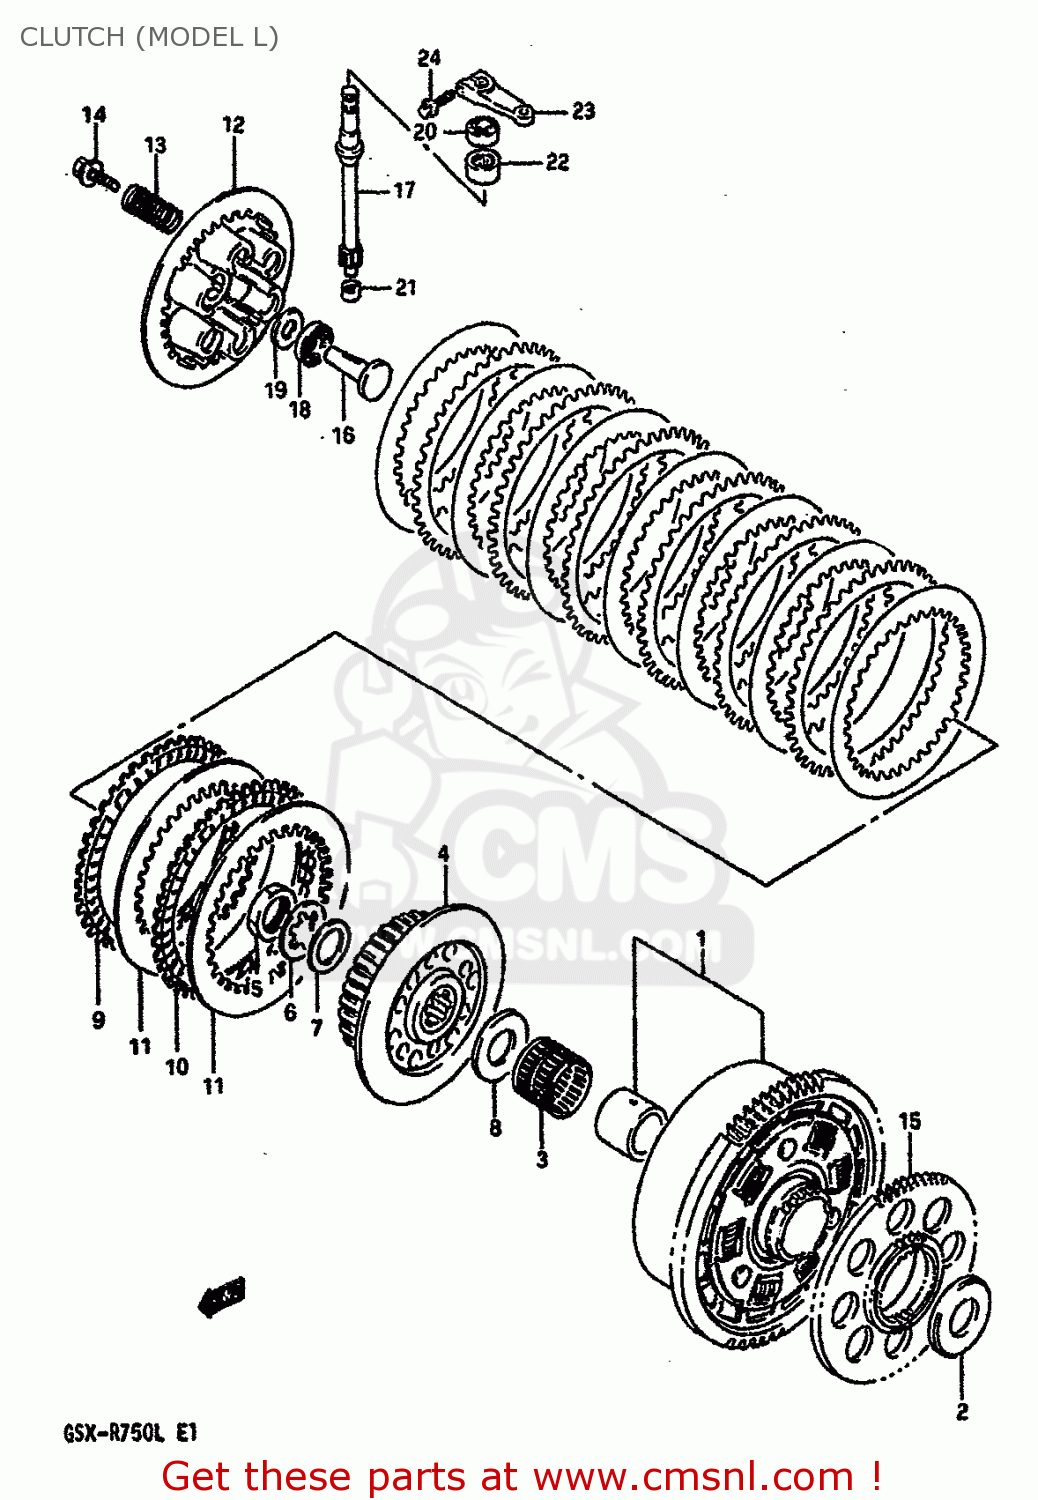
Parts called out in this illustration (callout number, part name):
1	GEAR ASSEMBLY,PRIMARY DRIVE
2	WASHER(25X54X2.5)
3	BEARING(35X40X35.8)
4	HUB,CLUTCH SLEEVE
5	NUT
6	WASHER,LOCK
7	WASHER
8	WASHER(25X50X2.5)
9	PLATE,CLUTCH DRIVE (NAS)
10	PLATE,CLUTCH DRIVE NO.2 (NAS)
11	PLATE,CLUTCH DRIVEN (NAS)
12	DISC,CLUTCH PRESSURE
13	SPRING
14	BOLT(6X25)
15	GEAR,GENERATOR DRIVE
16	RACK,CLUTCH RELEASE
17	PINION,CLUTCH RELEASE
18	BEARING(15X28X2)
19	WASHER
20	OIL SEAL
21	BEARING 10X14X10
22	BEARING(15X22X12)
23	ARM,CLUTCH RELEASE
24	BOLT
